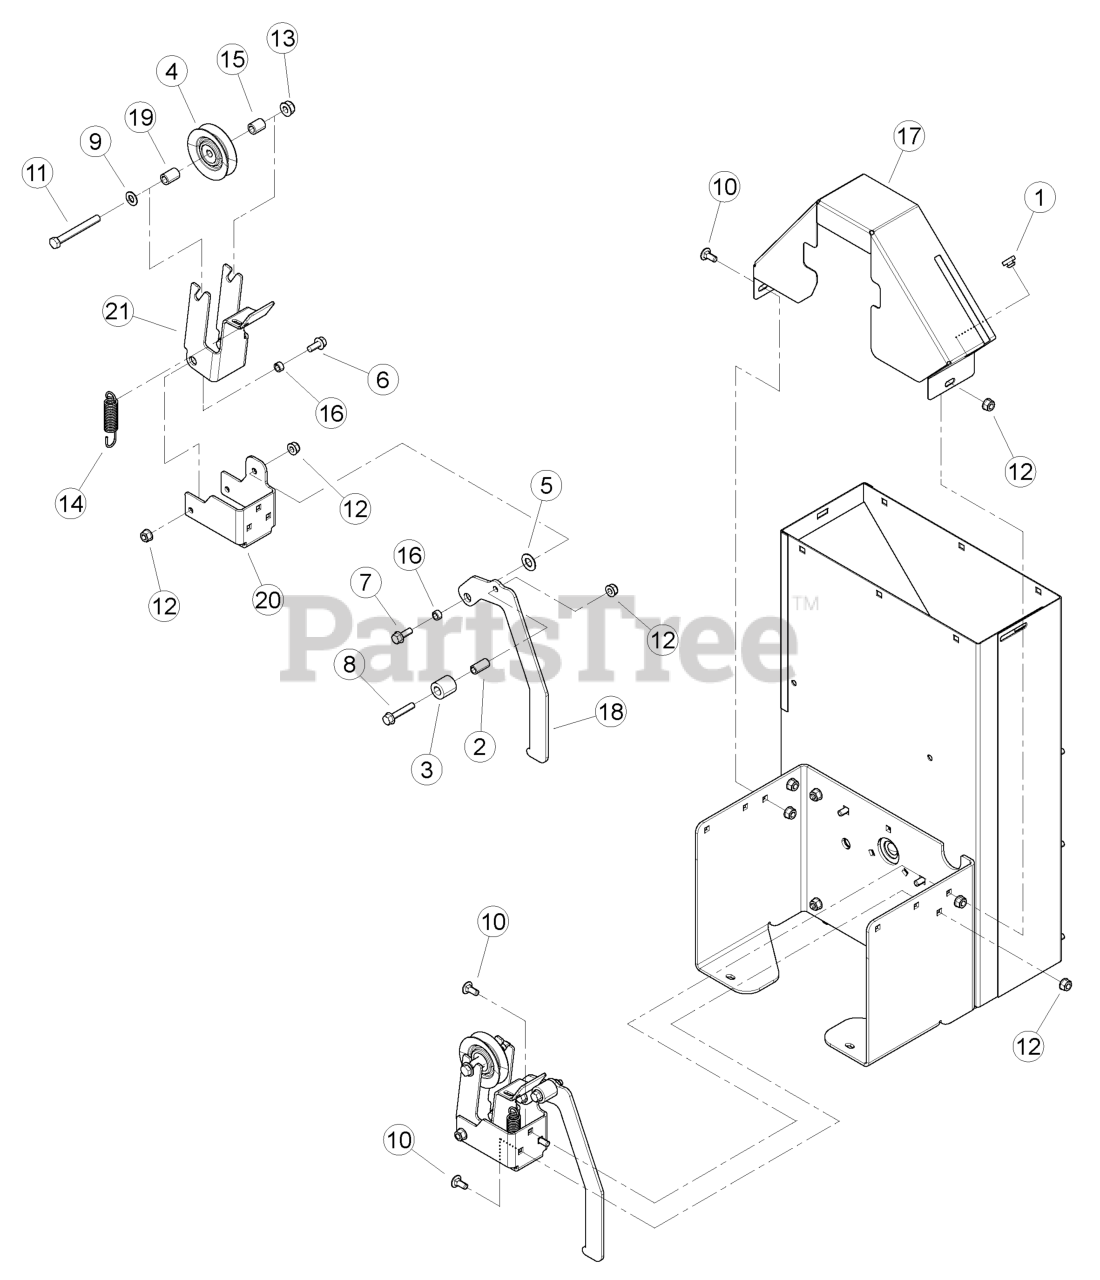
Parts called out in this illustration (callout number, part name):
1	BUMPER, RUBBER
2	SPACER, 0.5 × 1.00
3	ROLLER, 0.5 × 1.00 × 1.00 NYLON
4	IDLER, INSIDE
5	WASHER, 1/2 INCH NYLON
6	BOLT, 5/16 × 3/4 FLANGE NC
7	BOLT, 5/16 × 7/8 FLANGE NC
8	BOLT, 5/16 × 1-3/4 FLANGE NC
9	WASHER, 3/8 SAE FLAT ZP
10	BOLT, 5/16 × 3/4 GR5 CRG NC ZP
11	BOLT, 3/8 × 3-1/4 HEX HD GR5 ZP
12	NUT, 5/16-18 NYLOCK FLANGE
13	NUT, 3/8-16 NYLOCK FLANGE
14	SPRING, 3/4" OD EXTENSION
15	SPACER, 3/4" LONG IDLER TUBE
16	SPACER, .50 × .25
17	SHIELD, UPPER
18	HANDLE, ENGAGEMENT
19	SPACER, 5/8 OD × 11 GA × 0.88
20	MOUNT, IDLER BRACKET
21	BRACKET, IDLER 3 IN CHIPPER
